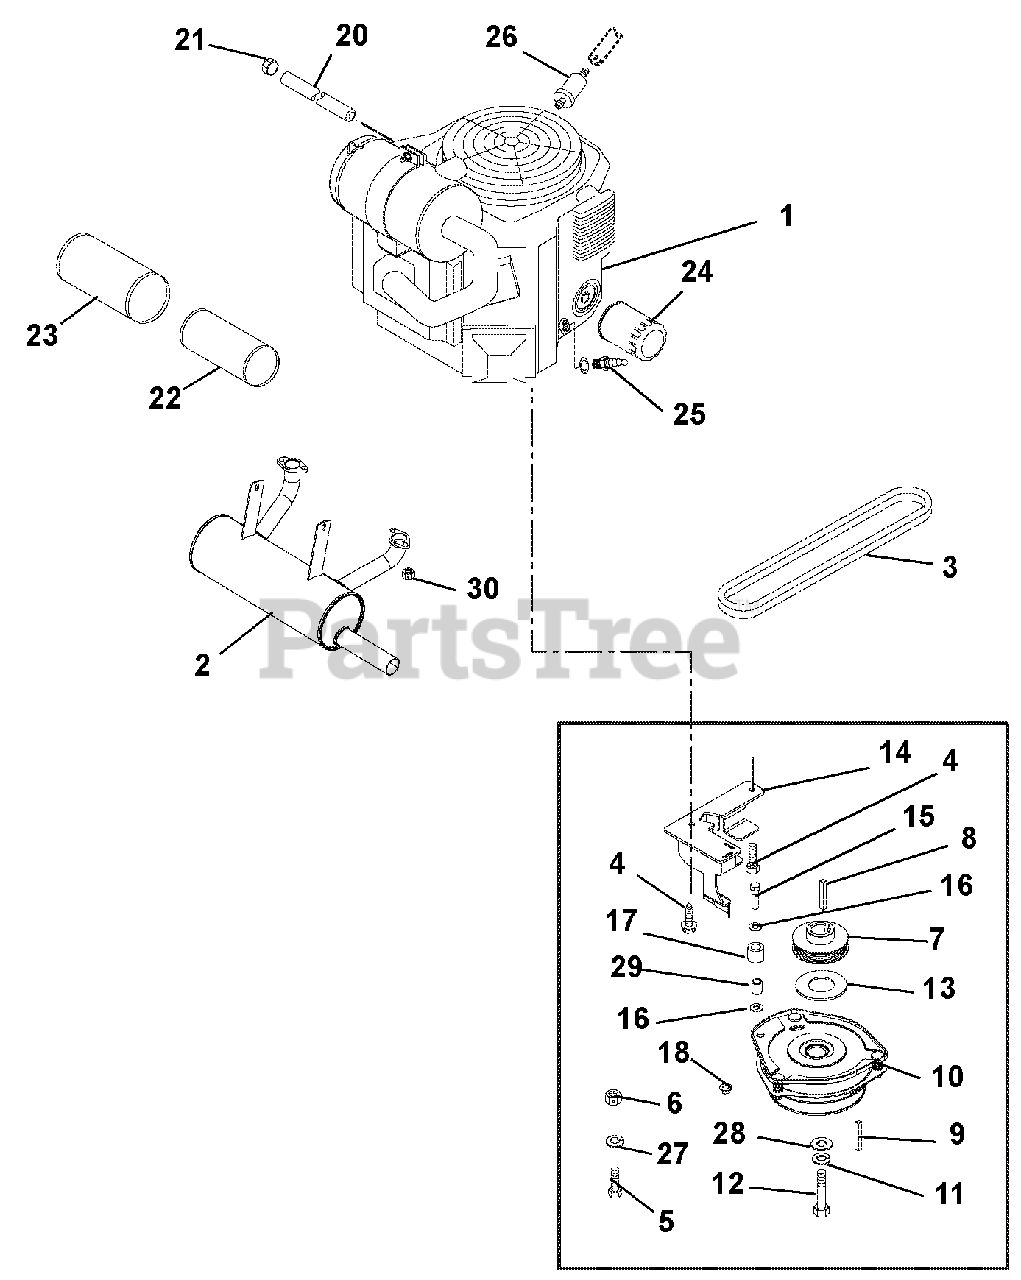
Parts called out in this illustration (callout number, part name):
1	Engine, Generac GTV990 (LPG)
2	Muffler, Generac GTV990 (LPG)
3	Belt, Poly-V
4	Screw, Tapping Hex Washer Head .38-16 x 1.50
5	Bolt, Hex .31-18 x 1.75 Grade 5
6	Nut, Locking Top Flange .31-18
7	Sheave, Poly V 1.27 x 3.275
8	Key, Square .25 x 1.25 x .25 SAE
9	Key, Straight .25 x 1.75 x .25
10	Clutch, Electric
11	Washer, Locking .44 x .109
12	Bolt, Hex .44-20 x 2.25 Grade 5
13	Washer, 1.13ID x 1.75OD x .048 Steel
14	Anchor Clutch
15	Bolt, Hex .38-16 x 1.50 Grade 5
16	Washer, Flat Steel .406 x .812 x .065
17	Bumper, Rubber .62 x 1.0 x .88 LG
18	Nut, Locking Top Flange .38-16
19	Cable Tie LG 5-1/2
20	Hose, Hydraulic .38-11-0K M6N0 – M6N0
21	Pipe Cap .38 NPT Female
22	Element, Inner Safety
23	Element, Outer Primary
24	Oil Filter
25	Spark Plug
26	Fuel Filter
27	Washer, Locking External .326 x .599 x .031
28	Washer, Flat Steel .469 x 2 x .25
29	Bushing, .407 x .625 x .813
30	Nut, Locking Top M8-1.25
